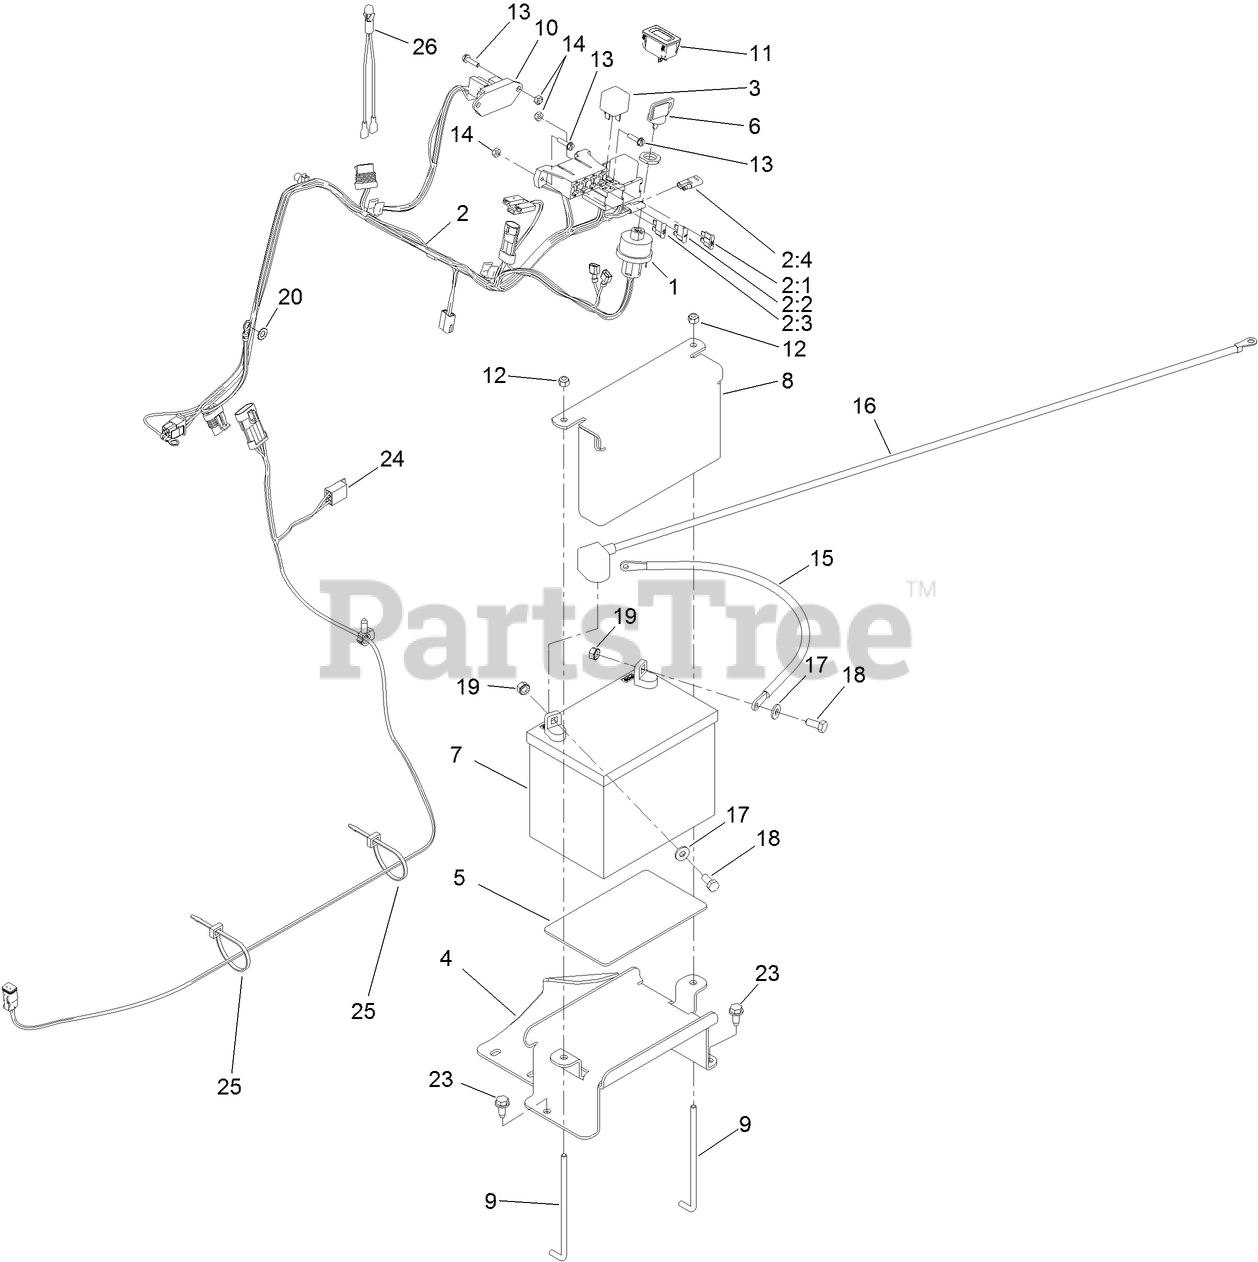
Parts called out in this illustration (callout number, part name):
1	SWITCH-IGNITION
2	HARNESS-WIRE
2:1	FUSE-BLADE, 30 AMP
2:2	FUSE-BLADE, 5 AMP
2:3	FUSE-BLADE, 20 AMP
2:4	CAP-PLUG
3	RELAY
4	TRAY-BATTERY
5	PAD-SKID, ANTI
6	KEY-IGNITION
7	BATTERY (340 CCA, WET)
8	PLATE-HOLD DOWN, BATTERY
9	HOLDOWN-BATTERY
10	MODULE-DELAY
11	HOURMETER
12	NUT-LOCK, NI
13	SCREW-HWH
14	NUT-LOCK, NI
15	CABLE-BATTERY, POSITIVE
16	CABLE-BATTERY, NEGATIVE
17	WASHER-FLAT
18	SCREW-HH
19	NUT-KEPS
20	WASHER-LOCK
23	SCREW-HWHTF
24	HARNESS-WIRE
25	TIE-CABLE
26	INDICATOR-LED, RED
